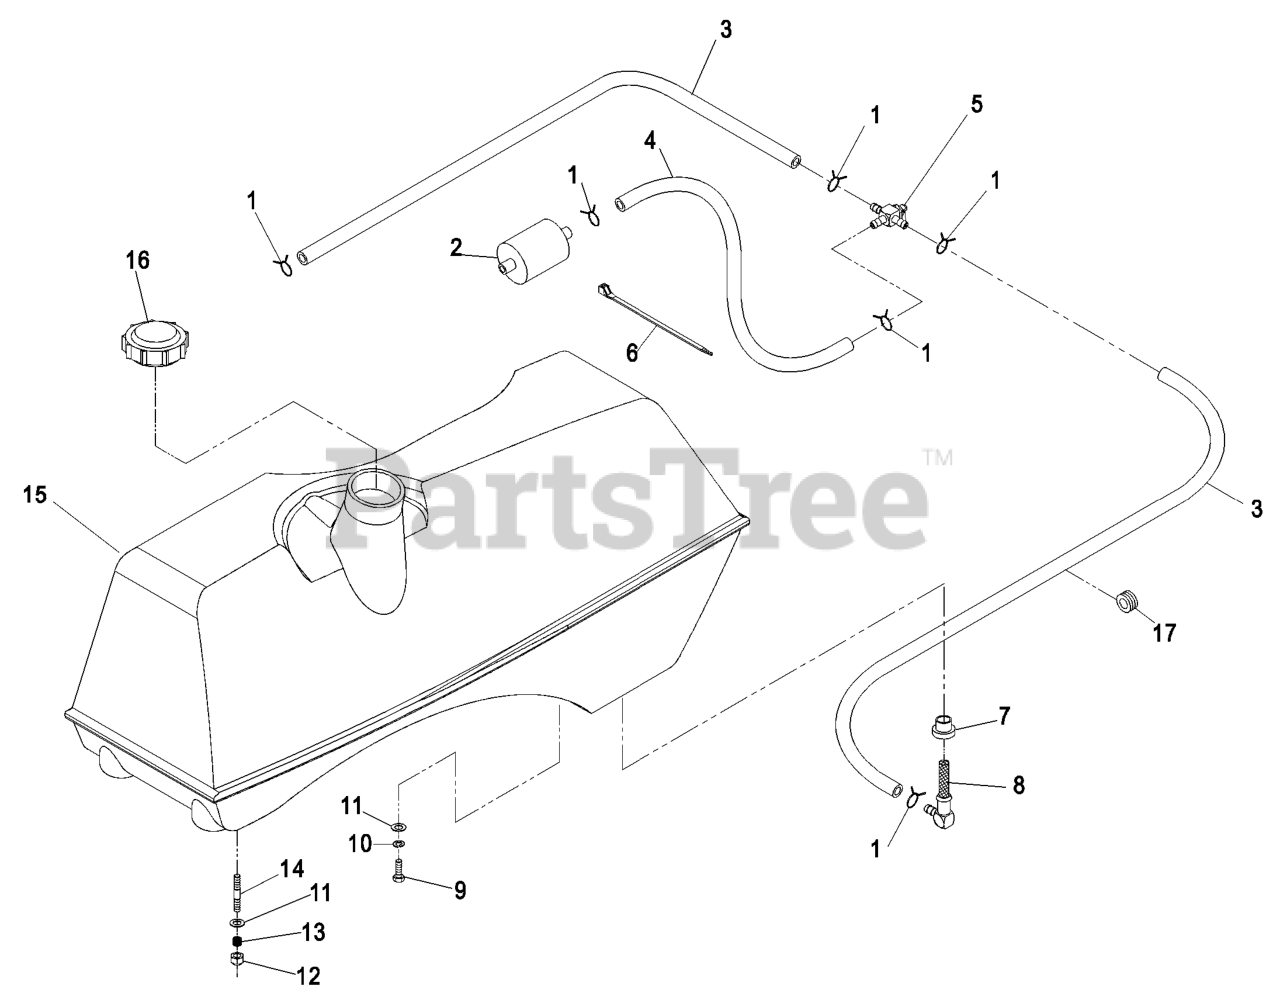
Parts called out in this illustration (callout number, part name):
2	Kohler Part No. 2405002 Fuel Filter
5	VALVE-FUEL
6	TIE-PLASTIC
8	ELBOW-TANK, FUEL
9	SCREW-HH
10	WASHER-LOCK
11	WASHER-PLAIN
12	NUT-LOCK, NI
13	SPRING-TANK, FUEL
14	STUD
16	CAP-FUEL
17	GROMMET
